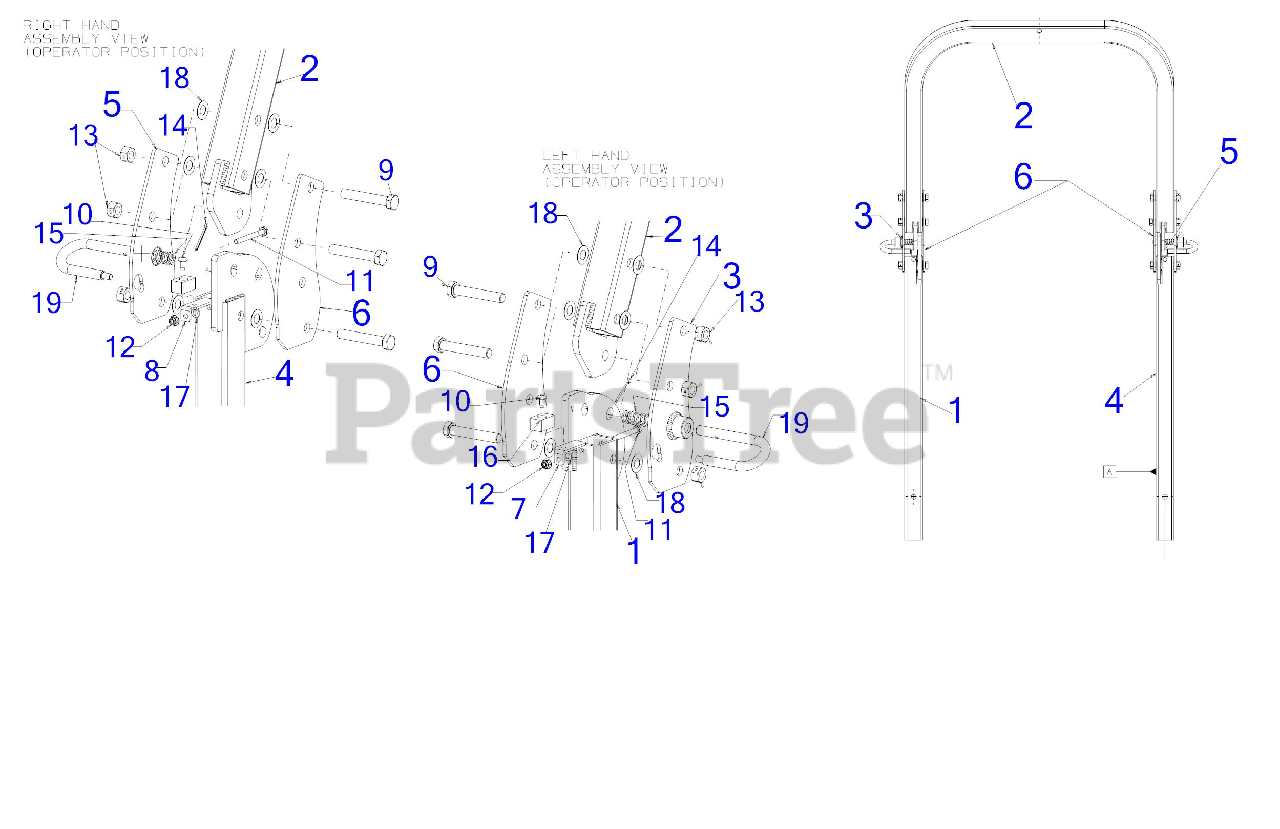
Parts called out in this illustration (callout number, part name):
9	SCREW-HEX 1/2-13 X 3.00
10	SCREW 1/4-20 x .5
11	SCREW 1/4-20 x 2.50 GR5
12	FLANGE LOCK NUT
13	HEX NUT CTR LK 1/2-13
14	COTTER PIN
15	COMPRESSION SPRING
16	ROPS BUMPER
17	FLAT WASHER .281 x .50 x .063
18	FLAT WASHER
19	ROPS ROD LOCK
